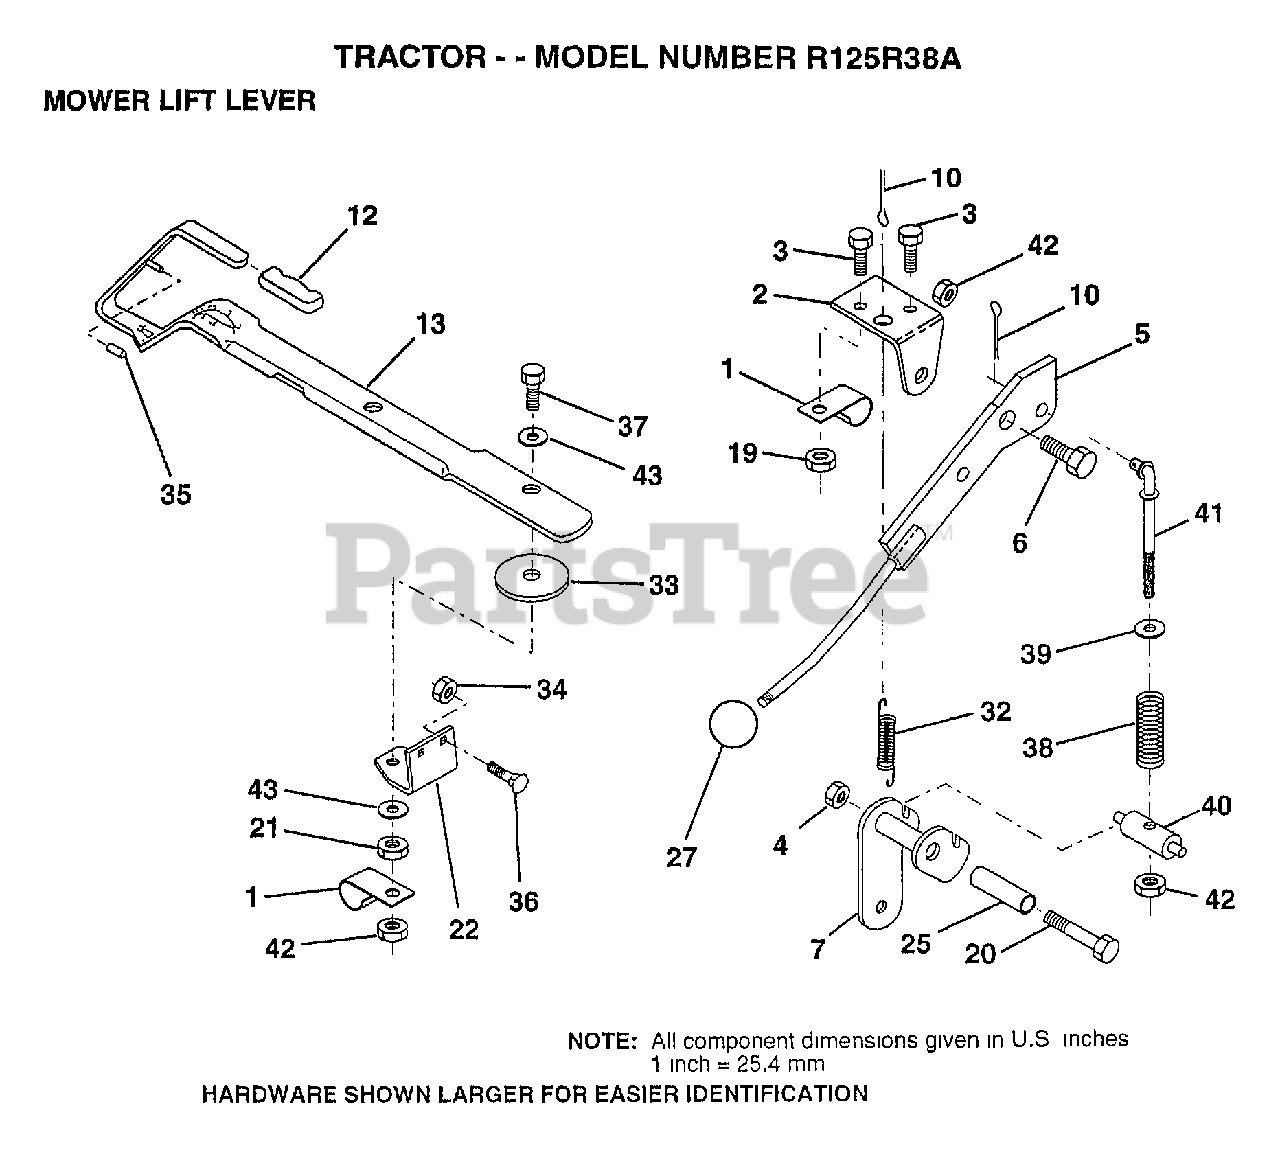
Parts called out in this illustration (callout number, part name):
1	"CLIP,INSULATOR"
2	BRKT CLUTCH
3	BOLT HXHD FIN
5	LEVER.ASM.CLUTCH
6	"BOLT, SHOULDER LT"
7	ARM.CLUTCH.ASM
10	COTTER PIN
12	GRIP HANDLE
13	LEVER LIFT LR
20	BOLT
21	LOCKNUT
22	LIFT LEVER BRKT
25	TUBE SPACER
27	KNOB T(3/8 HOLE)
32	SPRING EXT
33	WASHER
34	NUT
35	VINYL CAP RED
36	BOLT
37	BOLT
38	COMP CLUTCH SPRNG
39	WASHER HYT
40	TRUNNION
41	ROD TENSION CLUTC
42	NUT
43	WASHER
